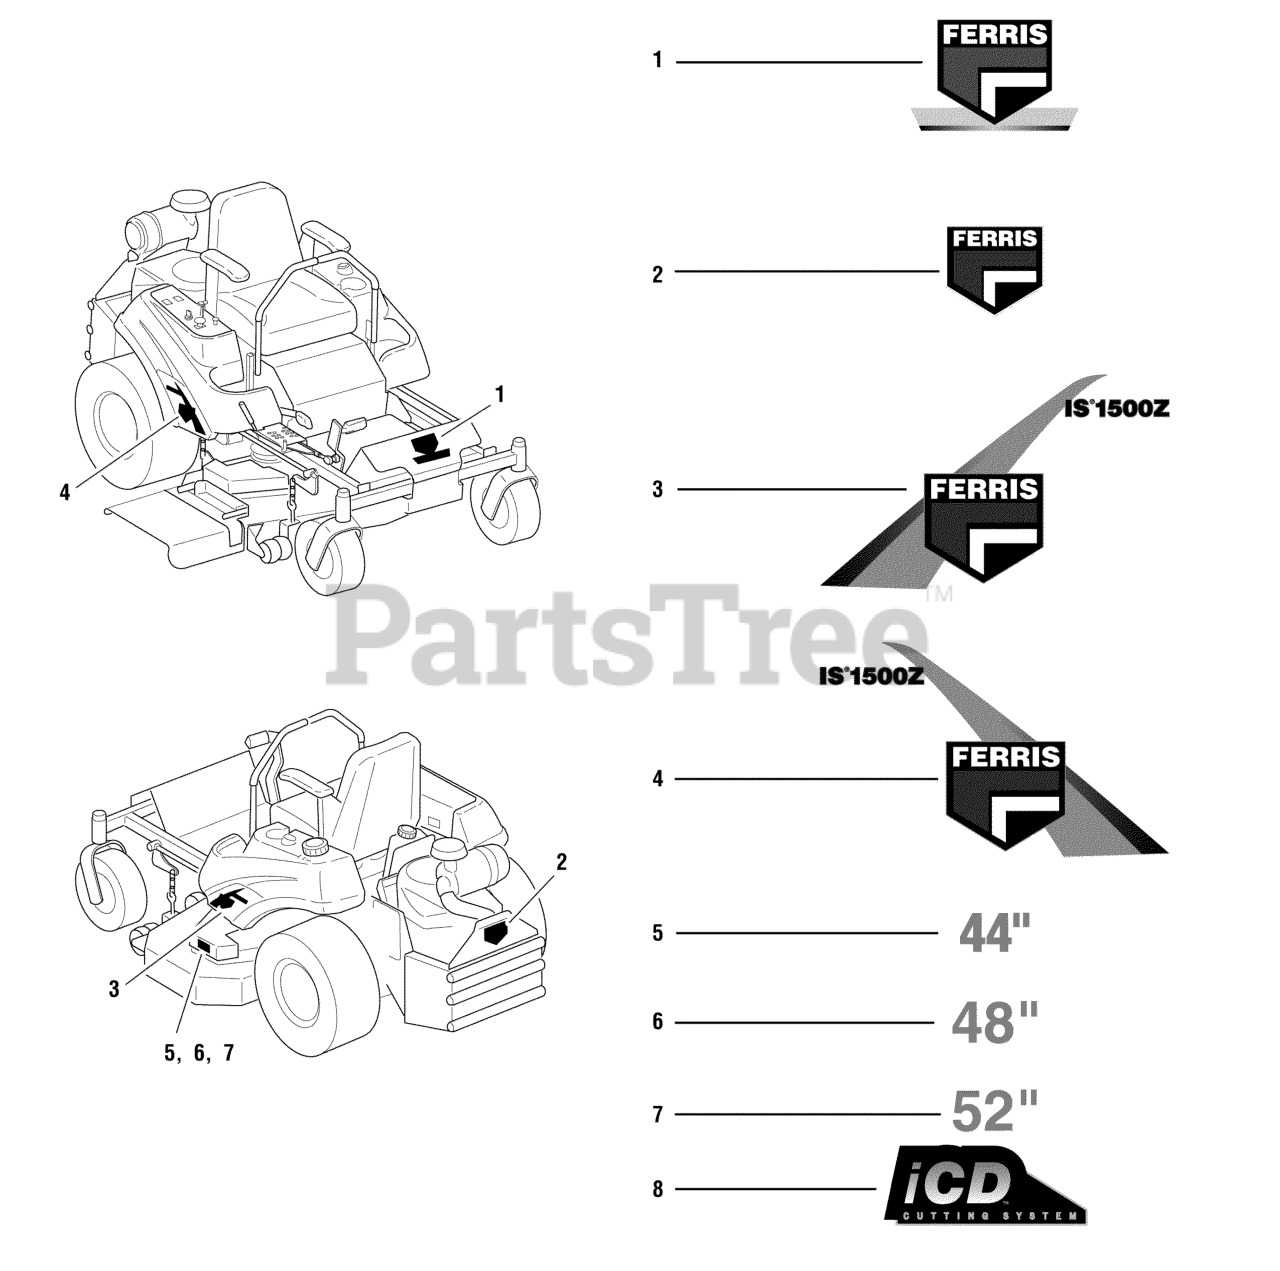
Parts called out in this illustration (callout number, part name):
1	DECAL, Ferris, Front
3	DECAL, Badge, LH, IS1500Z
4	DECAL, Badge, RH, IS1500Z
5	DECAL, 44"
6	DECAL, 48
7	DECAL, 52
8	DECAL, iCD CUTTING SYSTEM
